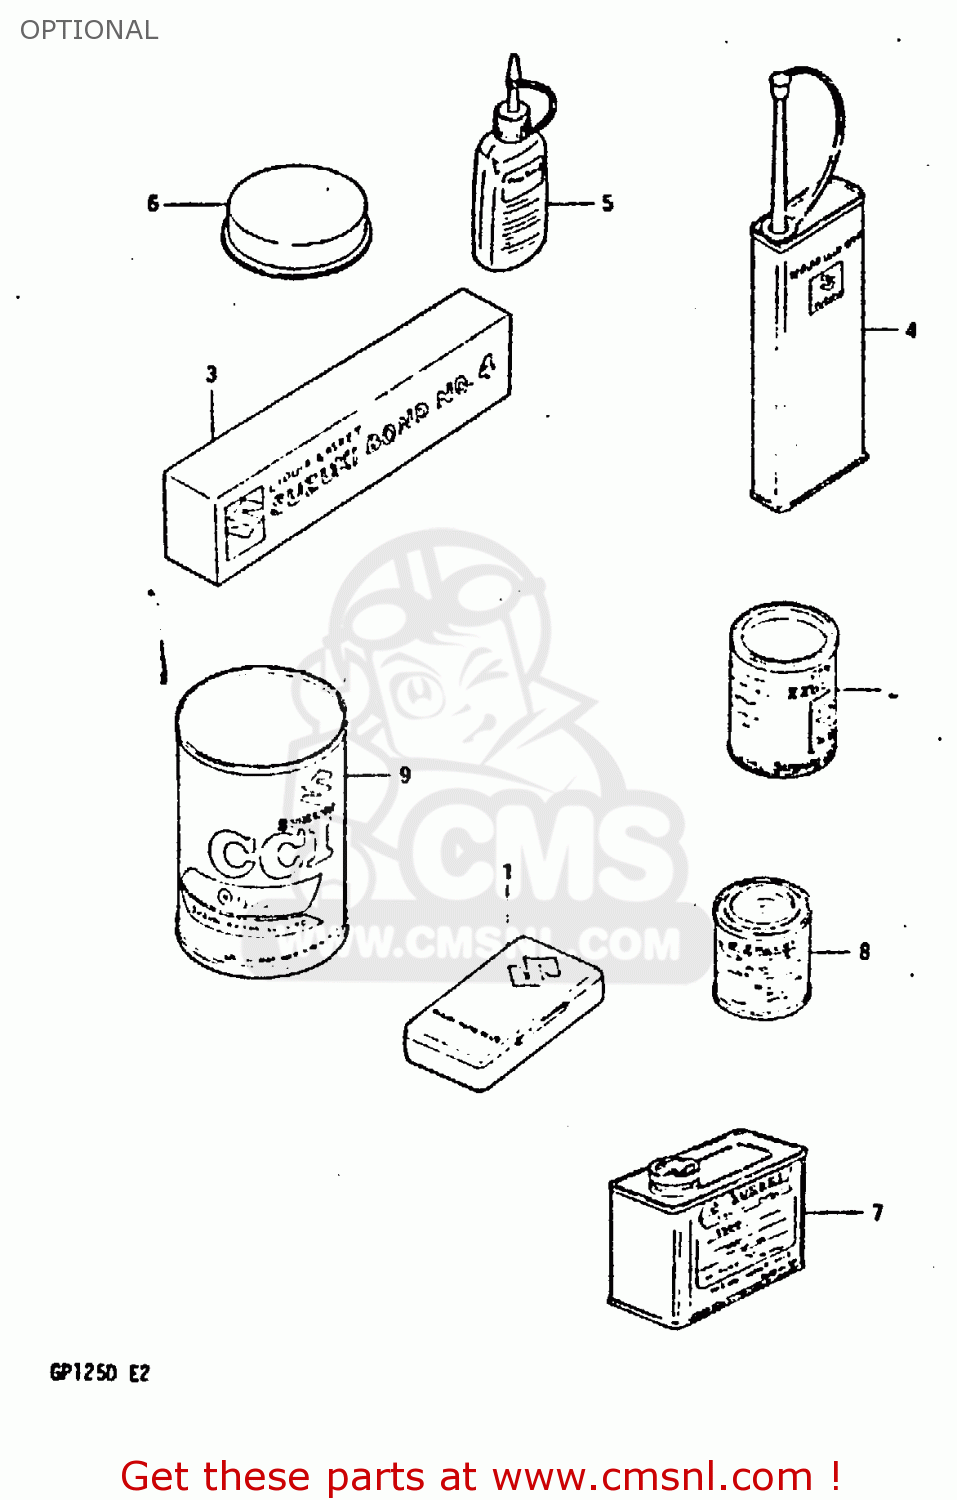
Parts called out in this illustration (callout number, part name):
1	TUBE REPARING TOOL
2	GREASE(C)EP2 LITHIUM 150G
3	BOND 1104
4	THREAD LOCK NO.1401 CLEAR 200G
5	THREAD LOCK NO
6	GREASE,PBC FOR BRK PAD 20G
7	PAINT (BLACK)
8	PAINT,BLACK
9	CCI OIL
